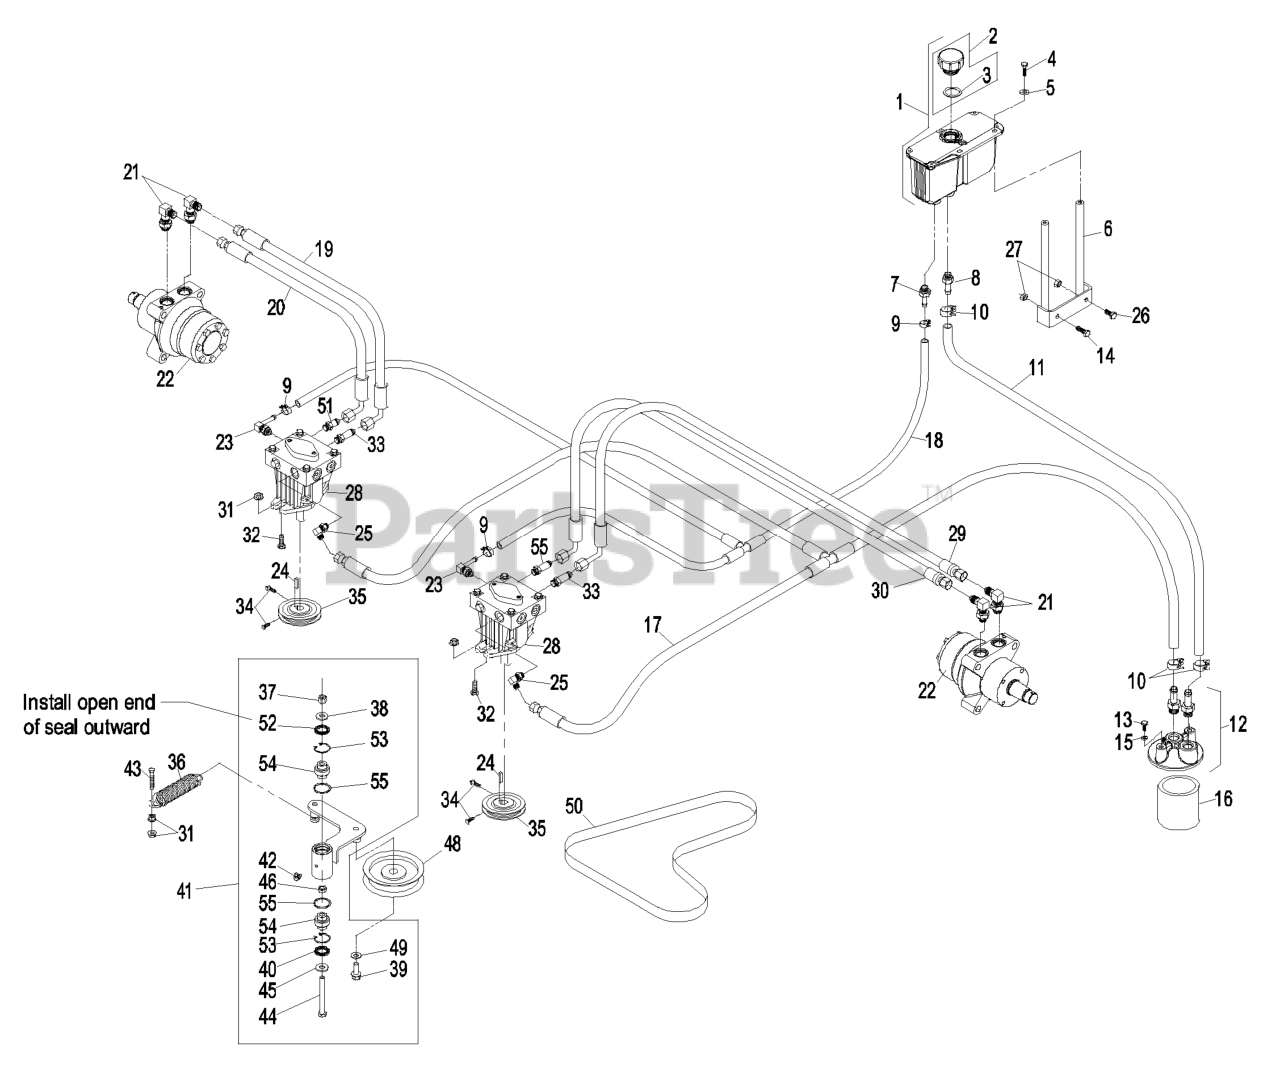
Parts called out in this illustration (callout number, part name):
1	HYD RESERVOIR ASM
2	KIT,HYD RES CAP W/GASKET
3	GASKET-CAP
4	SCREW-HH
5	WASHER-FLAT
6	STAND-RESERVOIR
7	ADAPTER-STRAIGHT
8	ADAPTER-STRAIGHT
9	CLAMP-HOSE
10	CLAMP-HOSE
11	HYD HOSE ASM
12	FILTER HEAD ASM
13	SCREW-HH
14	SCREW-HH
15	WASHER-LOCK
16	FILTER-25 MICRON, BI-DIRE
17	HYD HOSE ASM
18	HYD HOSE ASM
19	HOSE-REAR, RH
20	HOSE-REAR, RH
21	FITTING-HYD, 90 DEG
22	MOTOR-WHEEL
23	ELBOW-90 DEG
25	FITTING-ELBOW, 90 DEG
26	SCREW-HH
28	PUMP-HYD
29	HOSE-REAR, LH
30	HOSE-REAR, RH
31	NUT-HHF, WHIZ
32	SCREW-HH
33	ADAPTER-STR, LONG
34	SCREW-SET
36	SPRING-EXTENSION
37	NUT-LOCK, NI
38	WASHER-BELLEVILLE
39	SCREW-HHF
40	SEAL-LIP, DOUBLE
41	KIT, PUMP IDLER LHP/LCT
42	FITTING-GREASE, 90 DEG
43	SCREW-HH
44	SCREW-HH
45	WASHER-FLAT
48	PULLEY-IDLER, FLAT
49	WASHER-FLAT
50	BELT
51	ADAPTER-STRAIGHT
52	SEAL-LIP, SINGLE
53	RING-SNAP
54	BEARING-SPHERICAL
55	ADAPTER-STR, LONG
